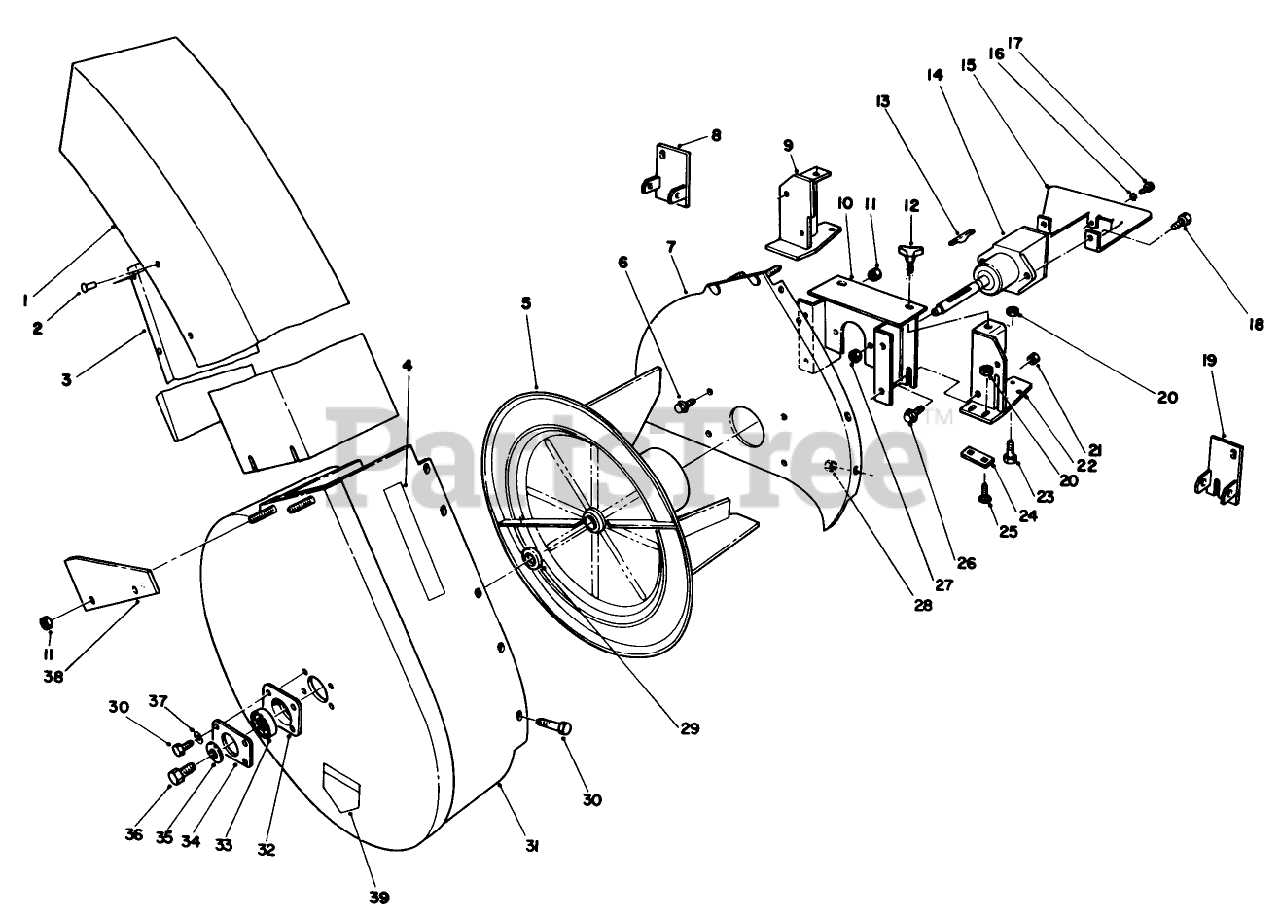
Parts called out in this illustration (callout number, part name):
1	Chute Assembly (Incl. Ref. #2 & 3)
3	Deflector-Chute
4	Decal-Waming
5	Impeller
6	SCREW-HHF
7	Mounting Plate
8	Bracket-Deflector L.H.
9	LH BRACKET ASM
10	Blower Mount
11	NUT-LOCK, NI
14	Asm-Gear Box
15	Cover-Gear Box
16	WASHER-LOCK, EXT
18	SCREW-HH
19	Bracket-Deflector R.H.
20	NUT-LOCK, CONE
21	NUT-JAM
22	RH BRACKET ASM
23	SCREW-HH
24	Plate-Bracket
25	BOLT-CARR
26	SCREW-HHF
27	NUT-LOCK, NI
28	NUT-LOCK, NI
29	SPACER-BEARING
30	SCREW-HH
31	Blower Housing (Incl. Ref. #4)
32	CUP-BEARING
33	BEARING-BALL
34	Cover-Plate
35	SPACER
36	SCREW-HH, LOCK
37	WASHER-LOCK
38	Bracket
39	DECAL-DANGER
